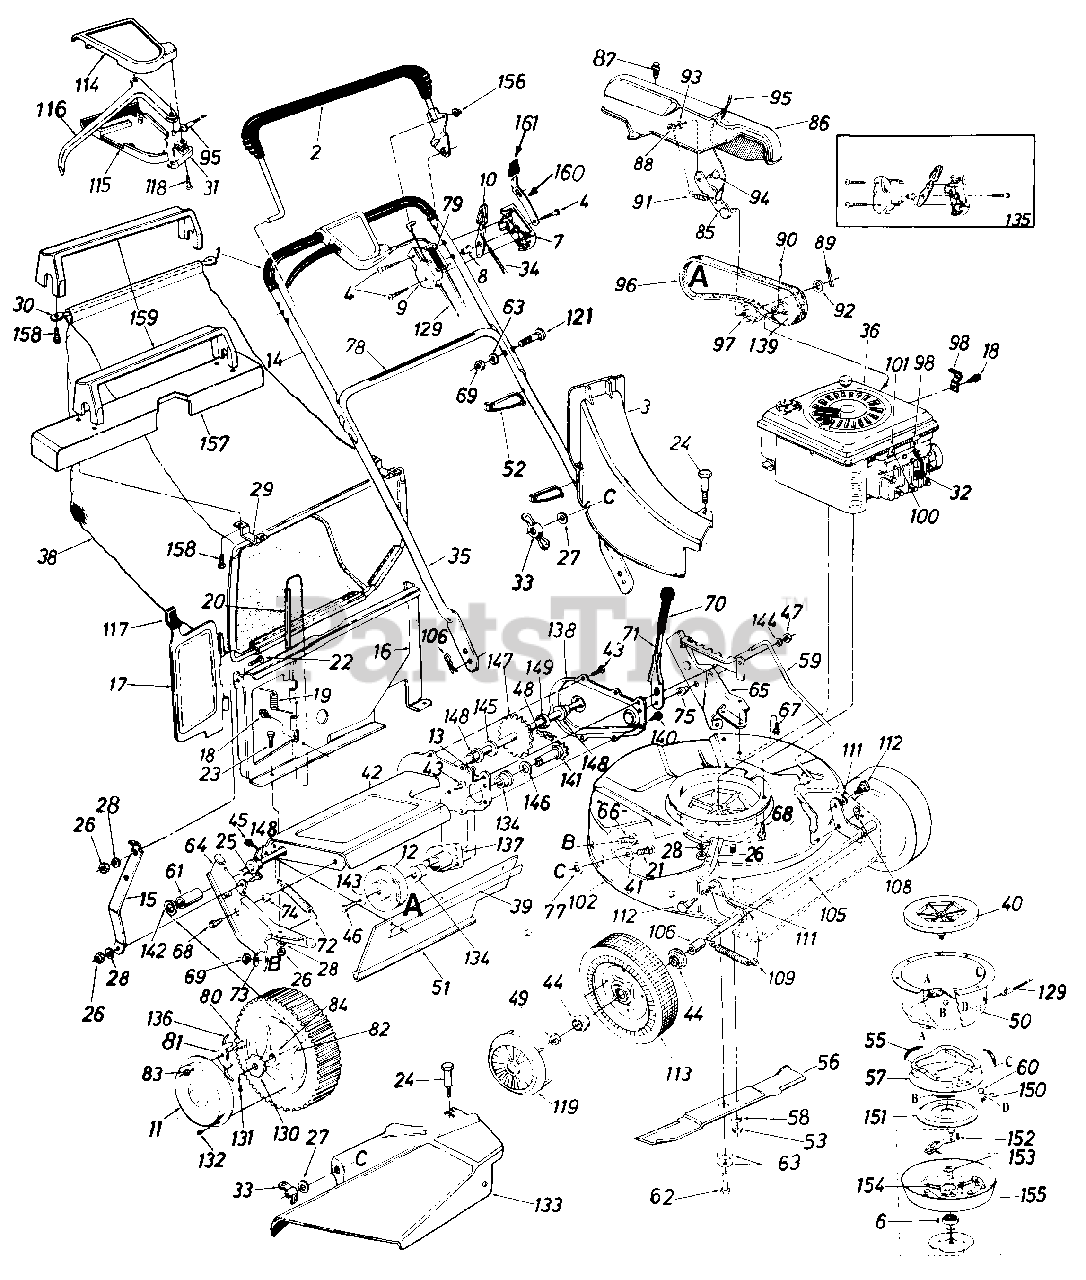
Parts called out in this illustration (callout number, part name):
2	Control Handle Ass'y. L.H.
3	Top Discharge Chute Ass'y.
4	Truss Mach. Scr. #12 x 1.50" Lg.
6	Ball Brg. .669" I.D. x 1.574"
7	Control Panel Half
8	Control Disc Pin
9	Clutch Panel Half
10	Throttle Control Lever
11	Hub Cap
12	1/2" V-Pulley
13	Cotter Pin 3/32" Dia. x .75"
14	Upper Handle Chrome
15	Panel Support Brkt.
16	Top Catcher Panel
17	Top Door
18	Hex B-Tap Scr. #10 x .38"
19	Torsion Spring
20	Pivot Pin
21	Carriaqe Bolt 1/4-20 x .62"
22	Truss Mach. Scr. 1/4-20 x 1/2" Lg.
23	Hex Bolt 1/4-20 x .50" Lg.
24	Shoulder Bolt .312 Dia. x .18 Lg. Special
25	Hex Bolt 1/4-20 x .62" Lg.
26	Hex Nut 1/4-20 Thd.
27	Fl-Wash. .280" I.D. x .620"
28	L-Wash. 1/4" I.D.
29	Front Grass Catcher Frame
30	No Part Description Supplied
31	S.P. Control Cover
32	Spark Plug Insulator
33	Wing Nut
34	Throttle Control Wire 45"
35	Lower Handle Chrome
36	Engine
38	21" Top Discharge Grass Bag
39	Retaining Strip
40	Fan Adapter
41	Fl-Wash. .344" I.D. x .62"
42	Chain Axle Ass'y.
43	Hex B-Tap Scr. 1/4" x .38" Lg.
44	Flange Ball Bearing 1/2" I.D.
45	Hex AB-Tap Scr. 1/4 x .62"
46	Hex Wash. TT-Tap Scr. 1/4-20
47	Hex Patch L-Nut 3/8-24 Thd.
48	#48 Chain .500" Pitch x .30 Links
49	Hex L-Nut 1/2-20 Thd.
50	Clutch Housing
51	Rear Flap 3.75" x 17.30" Lg.
52	Cable Tie
53	Hex Nut 3/8-24 Thd. (Grade 8)
55	Extension Spring .35" O.D. x 1.75" Lg.
56	21" Blade
57	Brake Cup Cone
58	L-Wash. 3/8" I.D.
59	Height Adj. Rod 19.42" Lg.
60	Steel Ball .500" Dia.
61	Spacer .51" I.D. x .69" O.D. x .69" Lg.
62	Hex Cent. L-Bolt 3/8-24 x 2.0" Lg. (Grade 8)
63	Bell-Wash. 3/8" I.D.
64	R.H. Handle Wheel Brkt. Ass'y.
65	L.H. Handle Wheel Brkt. Ass'y.
66	Carriage Bolt 5/16-18 x .62"
67	Hex Wash. Hd. B-Tap Scr. 5/16-18
68	Hex Wash. Hd. TT-Tap Scr. 3/8-16
69	Hex Nut 5/16-18 Thd.
71	Height Adj. Lever
72	Extension Spring .50" O.D. x 3.80" Lg.
73	Bell-Wash. .345" I.D. x .88"
74	Spacer .385" I.D. x .502" O.D. x .270" Lg.
75	Shld. Spacer .500" Dia. x .100
77	Bolt Retainer 1/4 x .50" O.D.
78	Instruction Label
79	Control Label
80	Shld. Scr. .342" Dia. x .268
81	Pawl
82	Wheel Ass'y. Comp. Rear 8 x 1.75
83	Hex Ins. L-Nut 1/4-20 Thd.
84	Flange Ball Bearing 1/2" I.D.
85	Belt Idler Bracket Ass'y.
86	Belt Cover
87	Hex Wash. S-Tap Scr. 1/4-20 x .50" Lg.
88	Hex Nut 1/4-20 Thd.
89	Cotter Pin 1/8" Dia. x 1.00" Lg.
90	Spring Pin Spir. 3/16" Dia. x 1.00" Lg.
91	Extension Spring .33" O.D. x 1.12" Lg.
92	Fl-Wash. .531" I.D. x .930" O.D. x .050
93	L-Wash. 1/4" I.D.
94	Shld. Bolt .375" Dia. x .181
95	S.P. Cable 53.0" Lg.
96	"V"-Belt 1/2" x 32.0" Lg.
97	Fl-Idler Plastic 1.62" Dia.
98	Casing Clamp
100	Hex B-Tap Scr. #10 x .62"
101	Casing Clamp
106	Sleeve .526" I.D. x .690" O.D. x .880" Lg.
108	Intern. Cotter Pin 5/16" Dia.
109	Extension Spring .50" O.D. x 3.20" Lg.
111	Intern. L-Wash. 3/8 I.D.
112	Shld. Bolt .623" Dia. x .425
113	Front-Wheel Ass'y. Comp. 7 x 1 .75
114	Self-Propelled Control Cover
115	Self-Propelled Control Cover
116	Control Lever
117	Door Grip
118	Fl-"C"-Sunk Hd. Tap Scr. #10 x .75" Lg.
119	Hub Cap
121	Curved Carr. Bolt 5/16-18 x 1.38" Lg.
129	Blade Brake/Clutch Cable 46"
130	Ratchet Wheel 1.62" O.D.
131	Cotter Pin 1/8" Dia. x 1.00" Lg.
132	Pan Hd. Tap Scr. #12 x .50" Lg.
133	Side Chute Deflector Ass'y.
134	Flange Bushing
135	Kit Control Housing Comp.
136	Spring Nylon
137	Bearing Hub Flange Ass'y.
138	Chain Cover
139	Engine Pulley 1/2"
140	Hex Wash. S-Tap Scr. 1/4-20 x.50" Lg.
141	Sprocket Shaft Ass'y.
142	Fl-Wash. .531" I.D. x .93" O.D.
143	Bell-Wash. .265" I.D. x .75" O.D.
144	Fl-Wash. .385" I.D. x .87" O.D.
145	Fl-Wash. .51" I.D. x 1.0" O.D.
146	Fl-Wash. .62" I.D. x 1.12" O.D.
147	Rear Shaft Ass'y. 22.05" Lg.
148	Hex Flange Bearing .506" I.D. Plastic
149	Spacer .510" I.D. x 1.00" O.D. x .210" Lg.
150	Ball Block
151	Clutching Cone
152	Hex Tap L-Scr. 1/4-20 x .75"
153	Fl-Wash. .690" I.D. x 1.060" O.D.
154	Compression Spring .35" O.D. x 2.00" Lg.
155	Clutch Blade Housing Ass'y.
156	Push Cap
157	Catcher Frame Cover
158	Truss Mach. Tap Scr. 1" Lg.
159	Bag Handle
160	Lockout Spring
161	Spring Lever Knob
